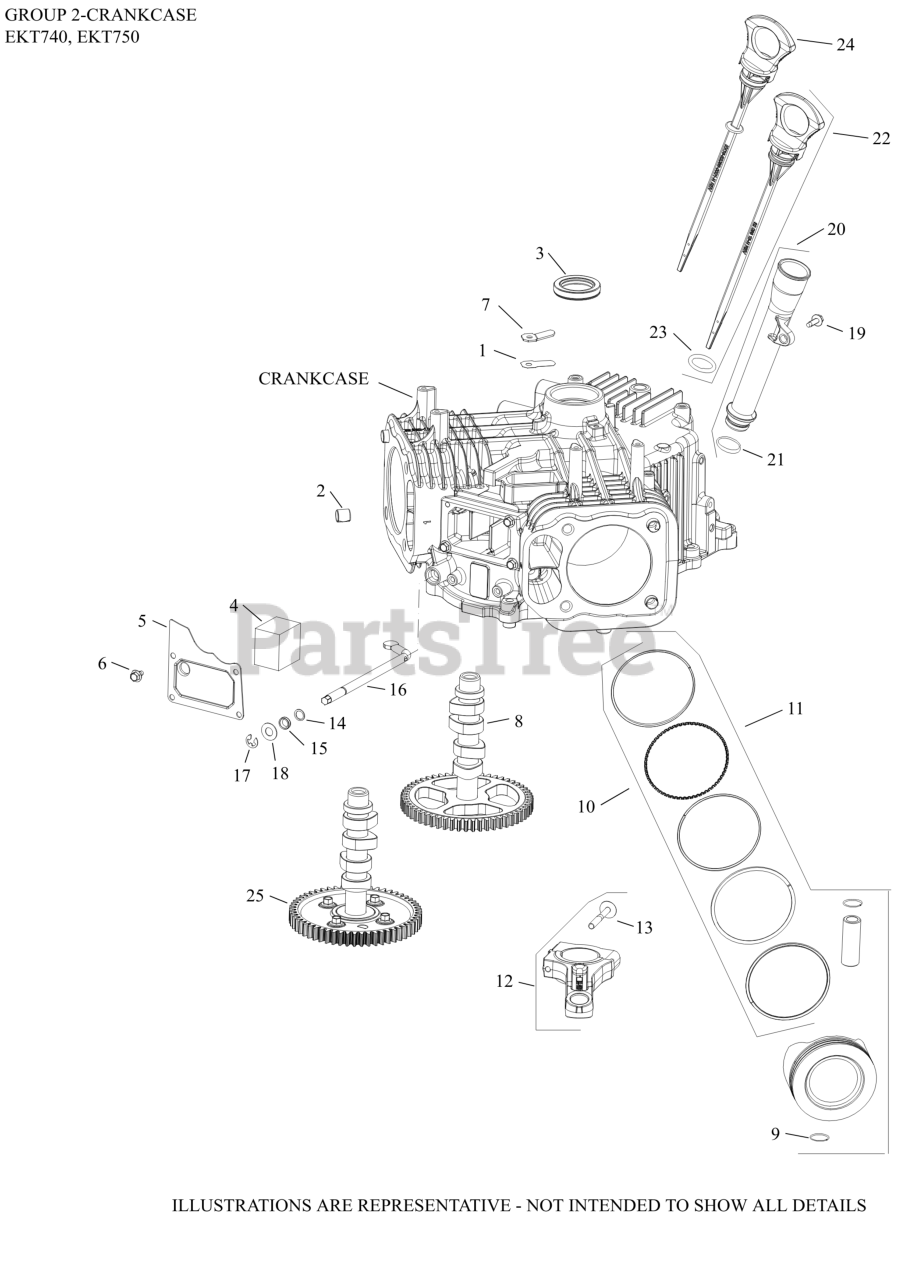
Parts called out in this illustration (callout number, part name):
1	REED, BREATHER
2	PIN, LOCATING
3	SEAL, OIL (HELIX LIP)
4	FILTER, BREATHER
5	COVER, BREATHER MEDIA
7	RETAINER, REED
8	CAMSHAFT ASSY
9	RETAINER, PISTON PIN
10	RING SET(STD)STYLE B-1.2mm Tp RING THICK
10	RING SET(.08)STYLE B-1.2mm RING THICK
10	RING SET(.25)STYLE B-1.2mm Tp RING THICK
10	RING SET(.50)STYLE B-1.2mm Tp RING THICK
11	KIT,PSTN/RNG STYLE B(STD)
11	KIT,PSTN/RNG STYLE B(.08)
11	KIT,PSTN/RNG STYLE B(.25)
11	KIT,PSTN/RNG STYLE B(.50)
12	ROD, ASSY CON (STD)-USE 24 067 30-S
12	ROD, ASSY CON(.25mm) -USE 24 067 31-S
13	KIT, ROD BOLTS-(#25086677S)
14	WASHER, FLAT 11/32"
15	SEAL, GOVERNOR CROSS SHAFT
16	KIT, CROSS SHAFT
17	CLIP, RETAINER GOVERNOR SHAFT
18	WASHER, FLAT 9 MM
19	SCREW, THREAD FORMING
20	TUBE ASSEMBLY, OIL FILL
22	DIPSTICK, ASSY
